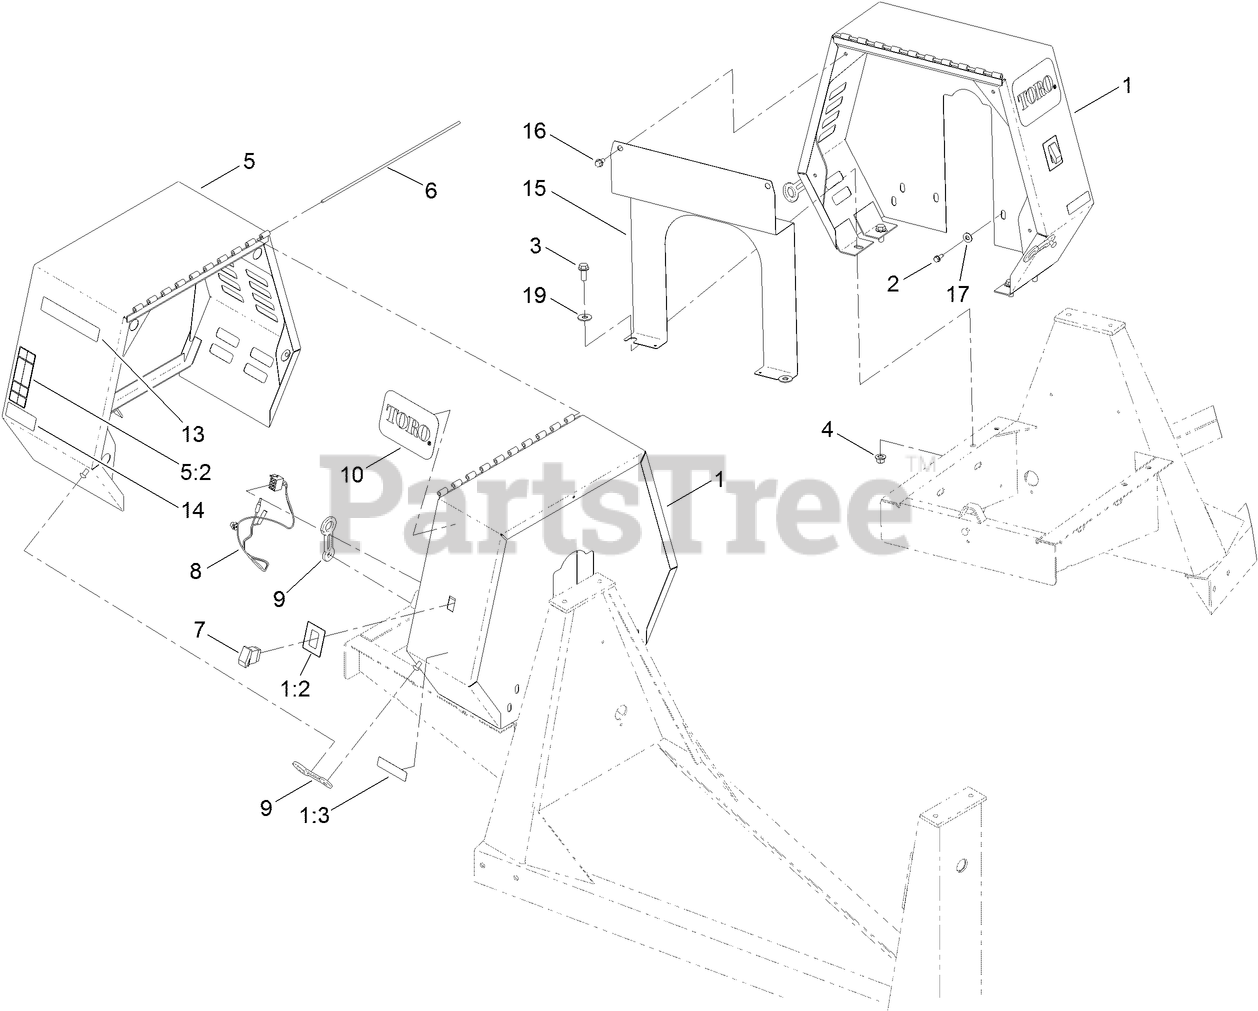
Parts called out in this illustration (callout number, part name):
1	STATIONARY COWL ASM
1:2	DECAL-STOP, ENGINE
1:3	DECAL-ARRESTER, SPARK
2	SCREW-HWHTF
3	SCREW-HHF
4	NUT-LOCK
5	MOVABLE COWL ASM
5:2	DECAL-WARNING
7	SWITCH
8	HARNESS-WIRE, MIXER
9	LATCH-RUBBER
10	DECAL
15	PLATE-ENGINE
16	SCREW-HWH
17	WASHER-FLAT
19	WASHER-FLAT
